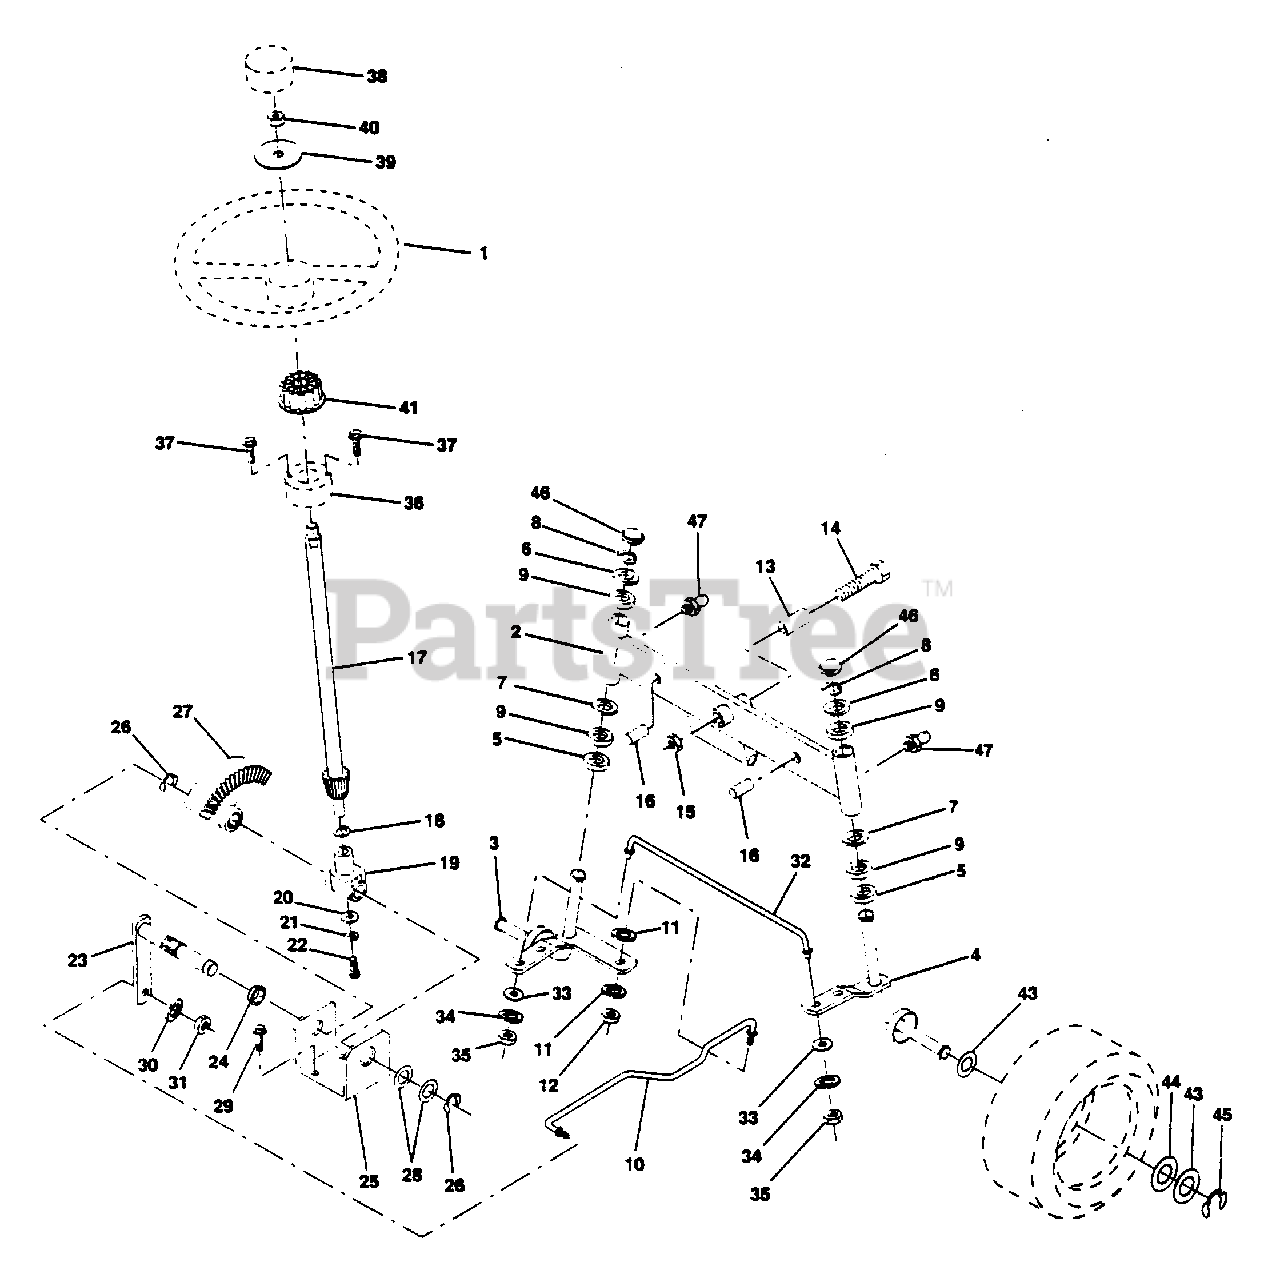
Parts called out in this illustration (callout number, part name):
1	Wheel Steering Auto Black
2	Axle Asm Fr LT W/gzks 38/42
3	Spindle Asm LH
4	Spindle Asm RH
5	Bearing Race Thrust Harden
6	Washer 25/32 X 1-5/8 X 16 Ga
7	Washer 27/32 X 1-1/4 X 16 Ga
8	Ring Klip #t5304-75
9	Bearing Col Strg Blk
10	Link Drag Sol Ball Jt 20 064
11	Washer Lock Hvy Hlcl Spr 3/8
12	Nut Fin Hex 3/8-24 Unf
13	Spacer Bearing Axle Front
14	Bolt Hex 5/8-11 Unc X 3-1/2
15	Nut Lock Flange 5/8-11 Unc
16	Pin Axle 5/8 X 1 55/1 54 Lg
17	Shaft Asm Strg 20 31 x 3/4 YP YT
18	Washer Thrust 515x 750x ??33
19	Support Shaft
20	Washer Shim 1/4 X 5/8 X 062
21	Washer Lock Hvy Helical 1/4
22	Screw Hex Socket 1/4-20 X 5/8
23	Shaft Asm Pittman
24	Nyliner Snap In
25	Bracket Steering
26	Ring Klip #t5304-75
28	Bearing Race Thrust Harden
29	Screw Thdrol 3/8-16x3/4 Ty-tt
30	Washer Lock Hvy Hlcl Spr 3/8
31	Nut Fin Hex 3/8-24 Unf
32	Rod Tie Wire Form 19 75 Elec
33	Washer 11/32 x 3/4 x 16 Ga.
34	Washer, Lock Hvy Hlcl Spr 5/16
35	Locknut 5/16-24 Unf
36	Bushing Strg Blk 742/747 Id
37	Screw Slftp #10-16 X 1/2 Ty-b
38	Insert Cap Strg Wh Aut
39	Washer 53 X 2 25 X 160 Zinc
40	Nut Hex Jam Toplock 1/2-20 Unf
41	Adapter Wheel Strg 758/ 753id
43	Washer 25/32 X 1 1/4 X 16 Ga
44	Washer 25/32 X 1-5/8 X 16 Ga
45	Ring Klip #t5304-75
46	Cap Spindle Fr Top Blk
47	Fitting Grease
